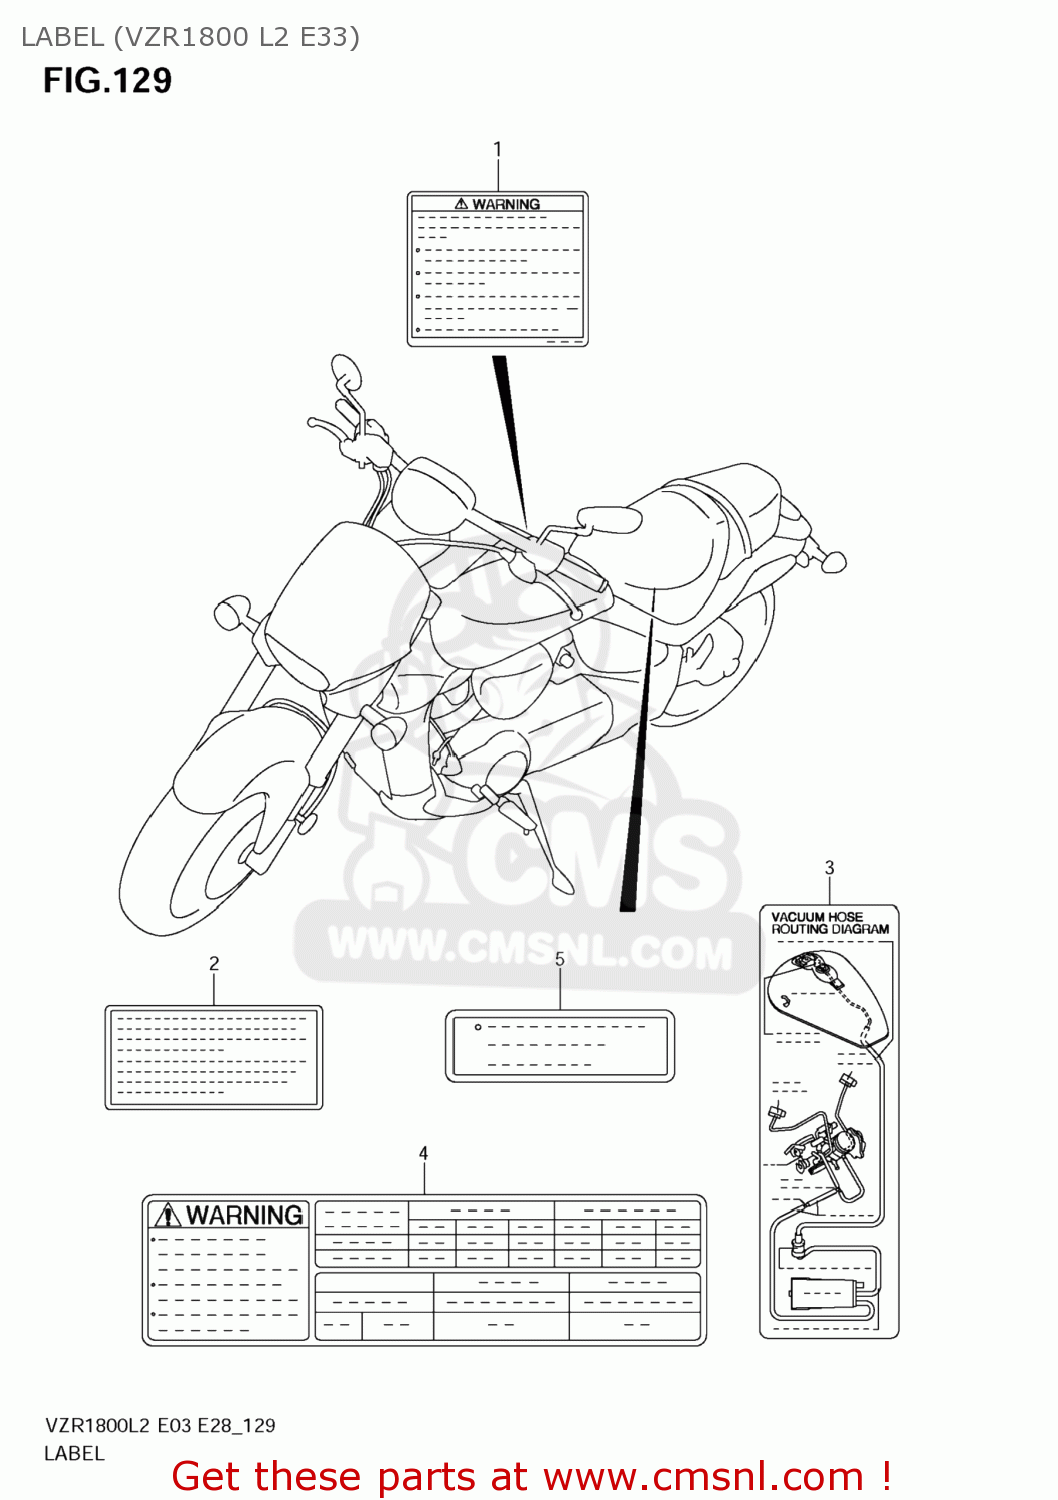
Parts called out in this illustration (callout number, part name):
1	LABEL,GENERAL WARNING
2	LABEL,MANUAL NOTICE
3	LABEL,VACUUM HOSE ROUTING
4	LABEL,TIRE INFORMATION
5	LABEL,FUEL INFORMATION
6	MANUAL,OWNER'S
7	MANUAL,SAFETY
